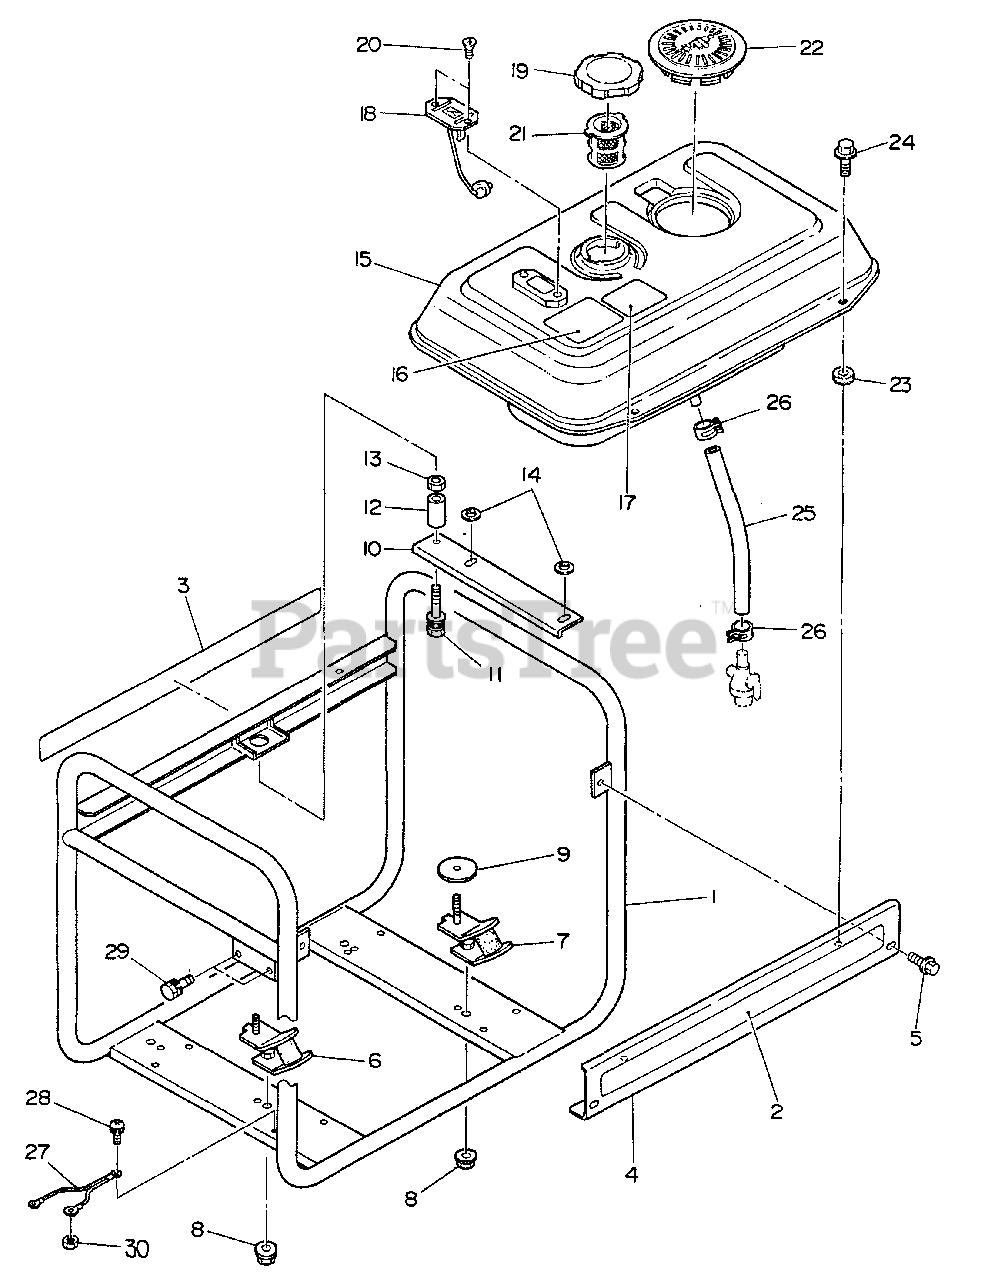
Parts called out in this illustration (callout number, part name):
1	PIPE FRAME ASSY
2	LABEL - MODEL EG-2400
3	LABEL - MODEL EG-2400
4	SIDE PLATE ASSY
5	BOLT - FLANGE
6	MOUNT, RUBBER
7	MOUNT, RUBBER
8	NUT - 8 -- FLANGE
10	STOPPER PLATE
11	BOLT
12	SPACER
13	NUT
14	WASHER
15	FUEL TANK ASSY
16	LABEL - CAUTION -- OPERATION
17	LABEL - DANGER
18	FUEL GAUGE ASSY
20	SCREW
21	FILTER, FUEL
22	COVER
23	WASHER - RUBBER
24	BOLT - FLANGE
25	RUBBER PIPE (11.5 X 17.5 X 230mm)
26	CLAMP, HOSE
27	LEAD - GROUND
28	SCREW
29	BOLT
30	NUT
